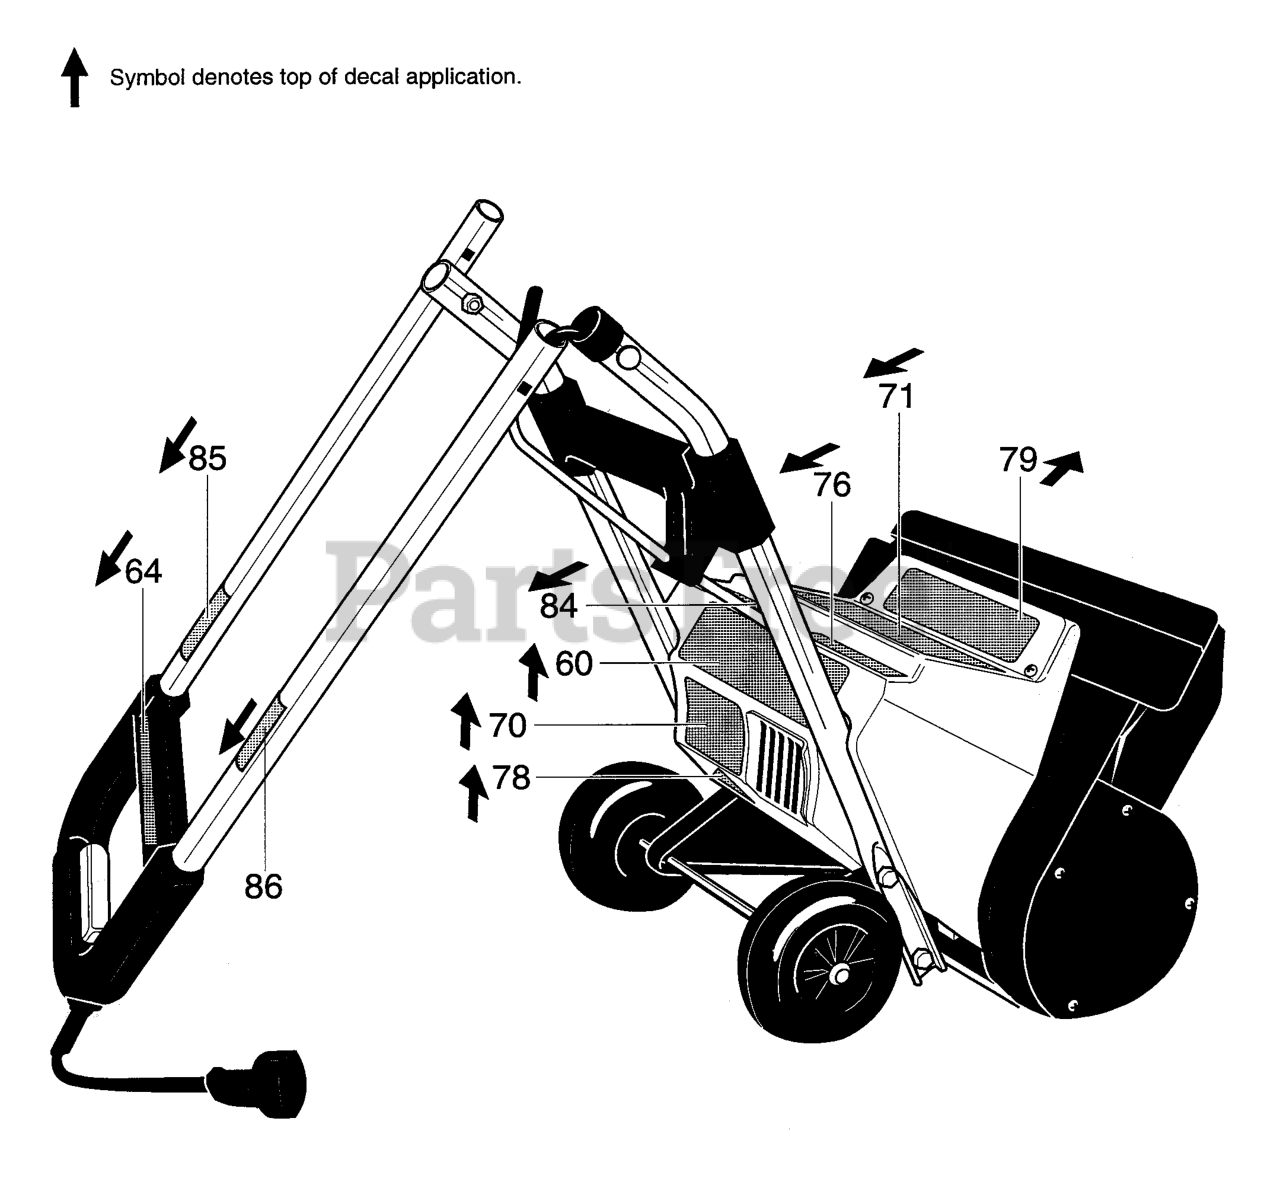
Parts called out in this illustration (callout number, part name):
60	DECAL, FOR SAFE OPERATION ENG/FR AUTOCOLLANT
64	DECAL TO START & STOP AUTOCOLLANT
70	NOT SERVICEABLE
71	DECAL, NAMEPLATE AUTOCOLLANT
76	DECAL, DISCHARGE CONTROL AUTOCOLLANT
79	DECAL, DANGER FOOT AUTOCOLLANT
84	DECAL,WARNING CUT-OUT AUTOCOLLANT
85	DECAL, MOTOR PROTECTION, ENG AUTOCOLLANT
86	DECAL, MOTOR PROTECTION, FR AUTOCOLLANT
